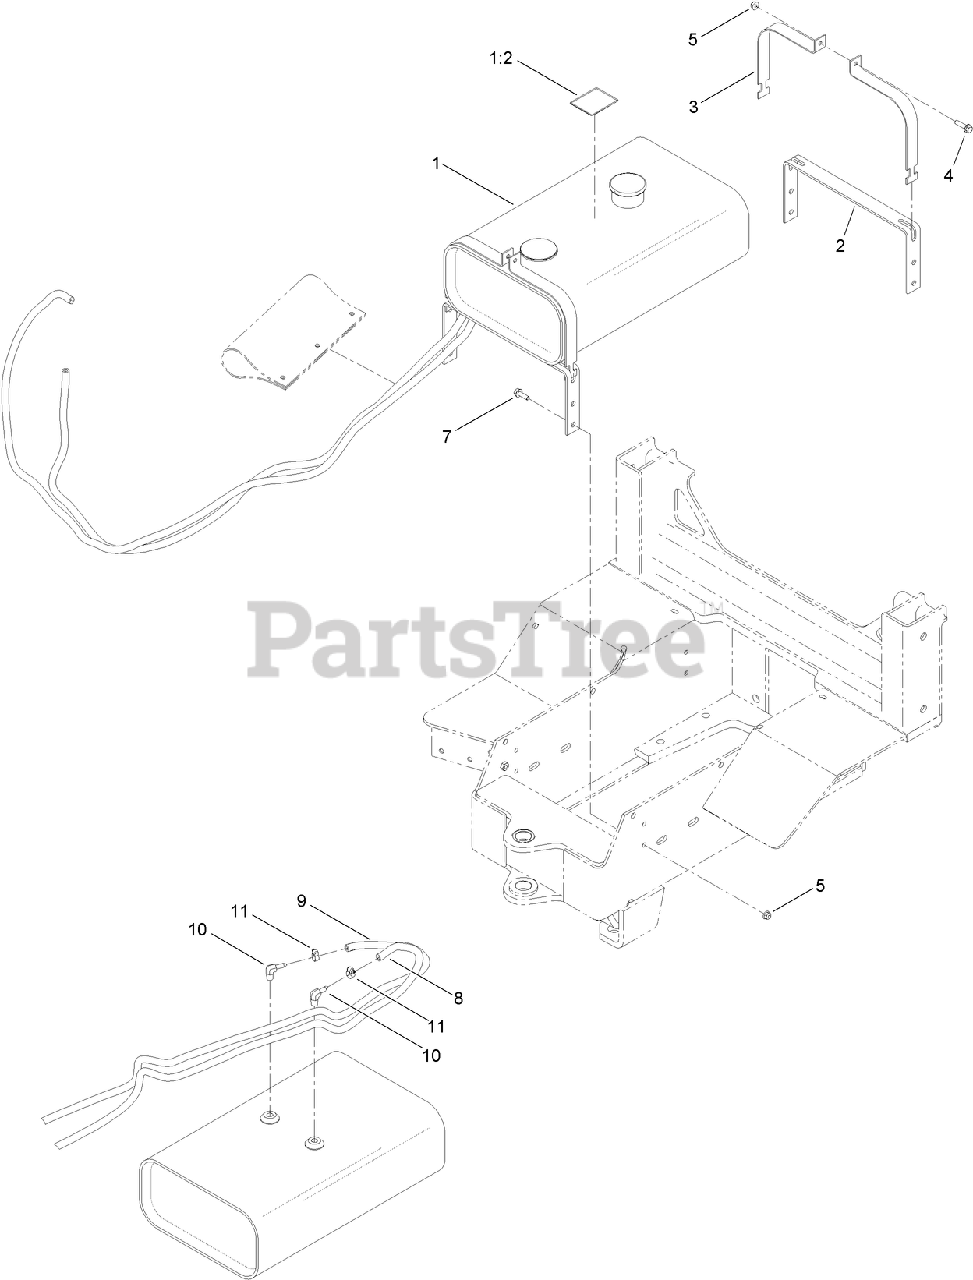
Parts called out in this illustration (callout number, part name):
1	FUEL TANK ASM
1:2	DECAL-DIESEL, ULTRA-LOW
2	BRACKET-TANK, FUEL
3	STRAP-TANK, FUEL
4	SCREW-HHF
5	NUT-HF, NI
7	SCREW-HHF
8	HOSE-FUEL
9	HOSE-FUEL
10	STEM-90 (BARB HOSE)
11	CLAMP-WORM
